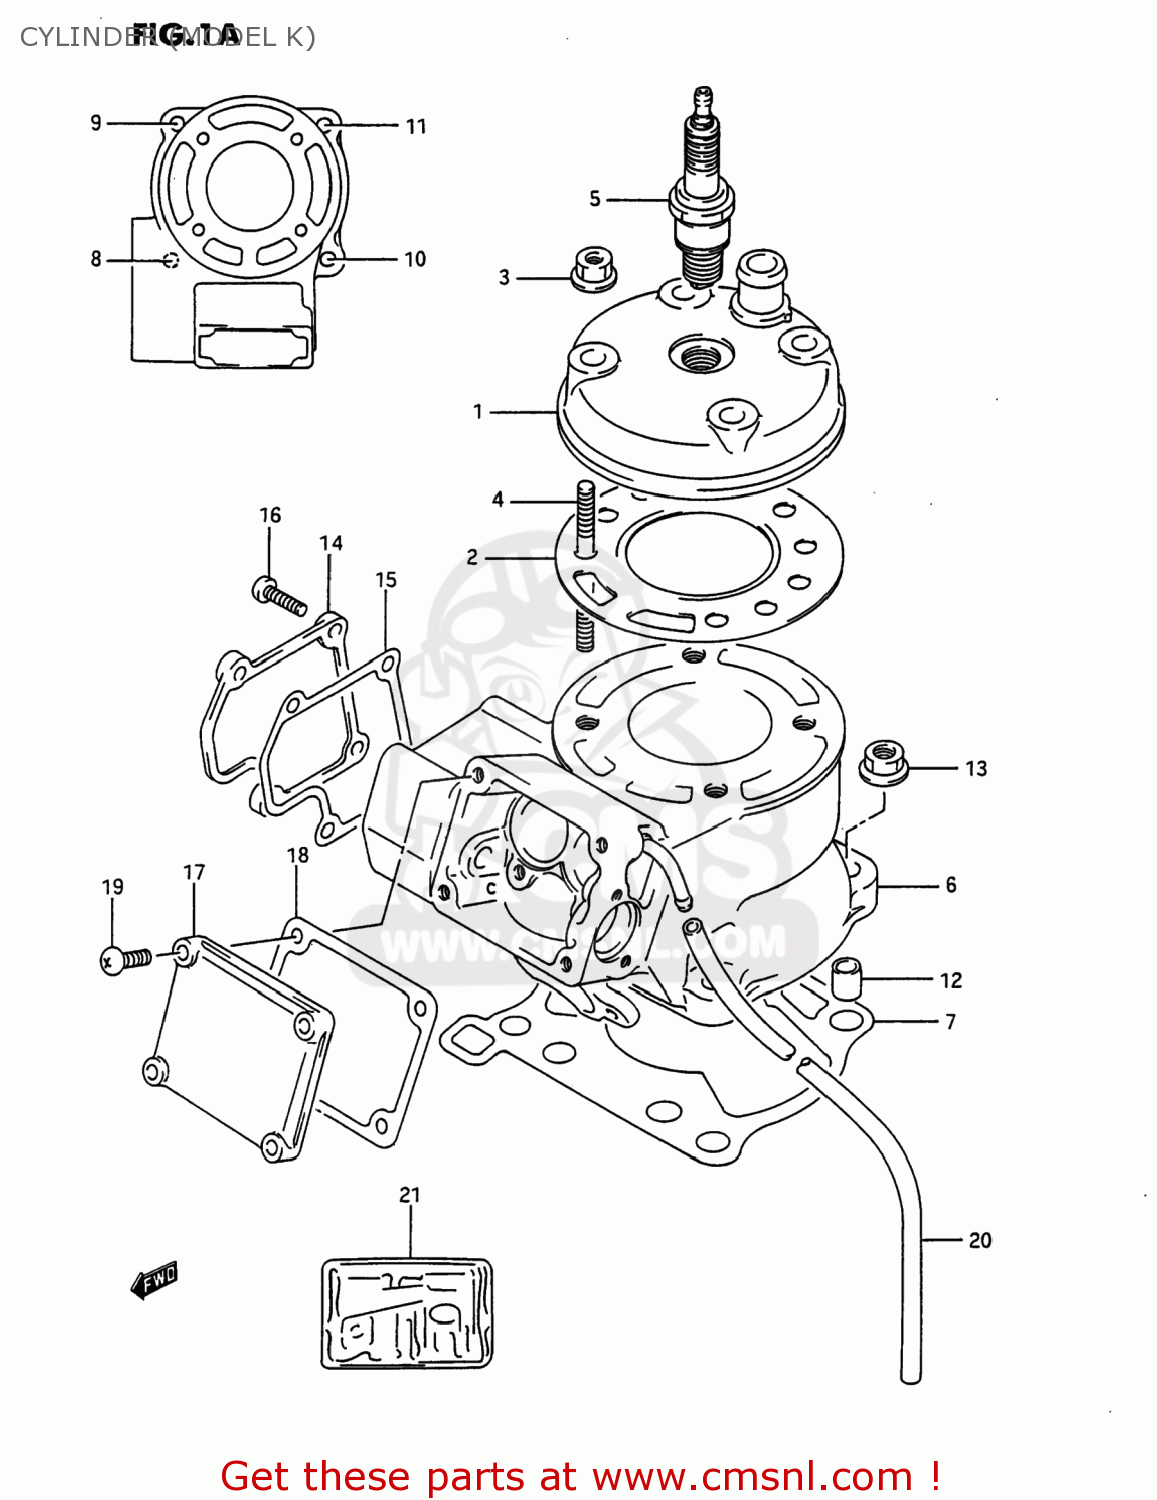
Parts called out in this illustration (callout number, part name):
1	HEAD,CYLINDER
2	GASKET,CYLINDER HEAD (MCA)
3	NUT
4	BOLT,STUD
5	SPARK PLUG B9ES
6	CYLINDER
7	GASKET,CYLINDER (NAS)
8	BOLT,STUD
9	STUD 8X25
10	BOLT,STUD
11	BOLT,STUD
12	PIN
13	NUT
14	COVER,CYLINDER NO.1
15	GASKET,CYLINDER COVER (NAS)
16	SCREW
17	COVER,CYLINDER
18	GASKET,CYL COVER NO.2 (NAS)
19	SCREW
20	HOSE(4X7X600)
21	GASKET SET (NAS)
